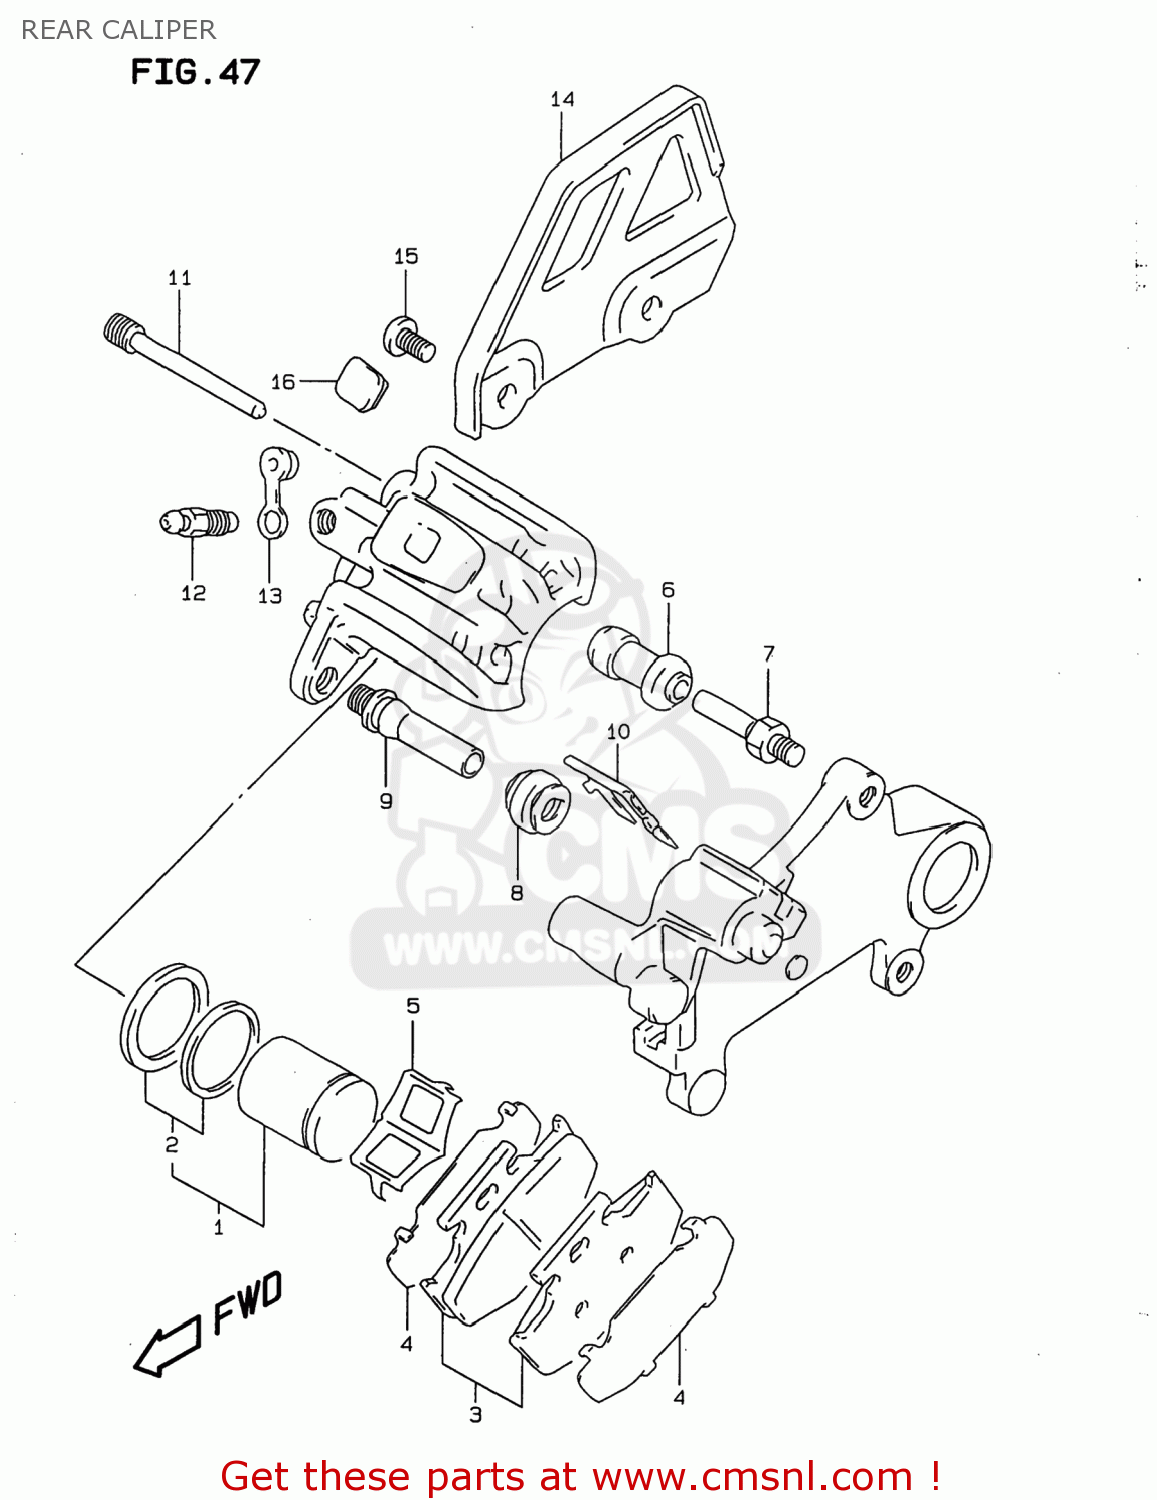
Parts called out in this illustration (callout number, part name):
1	PISTON SET
2	SEAL SET,PISTON
3	PAD SET (NAS)
4	SHIM
5	SPRING,PAD
6	BOOT
7	BOLT
8	BOOT
9	PIN
10	RETAINER,BRACKET
11	PIN,HANGER
12	BLEEDER
13	CAP,BLEEDER
14	GUARD,RR CALIPER
15	SCREW 6X12
16	COVER,RR CALIPER BODY
